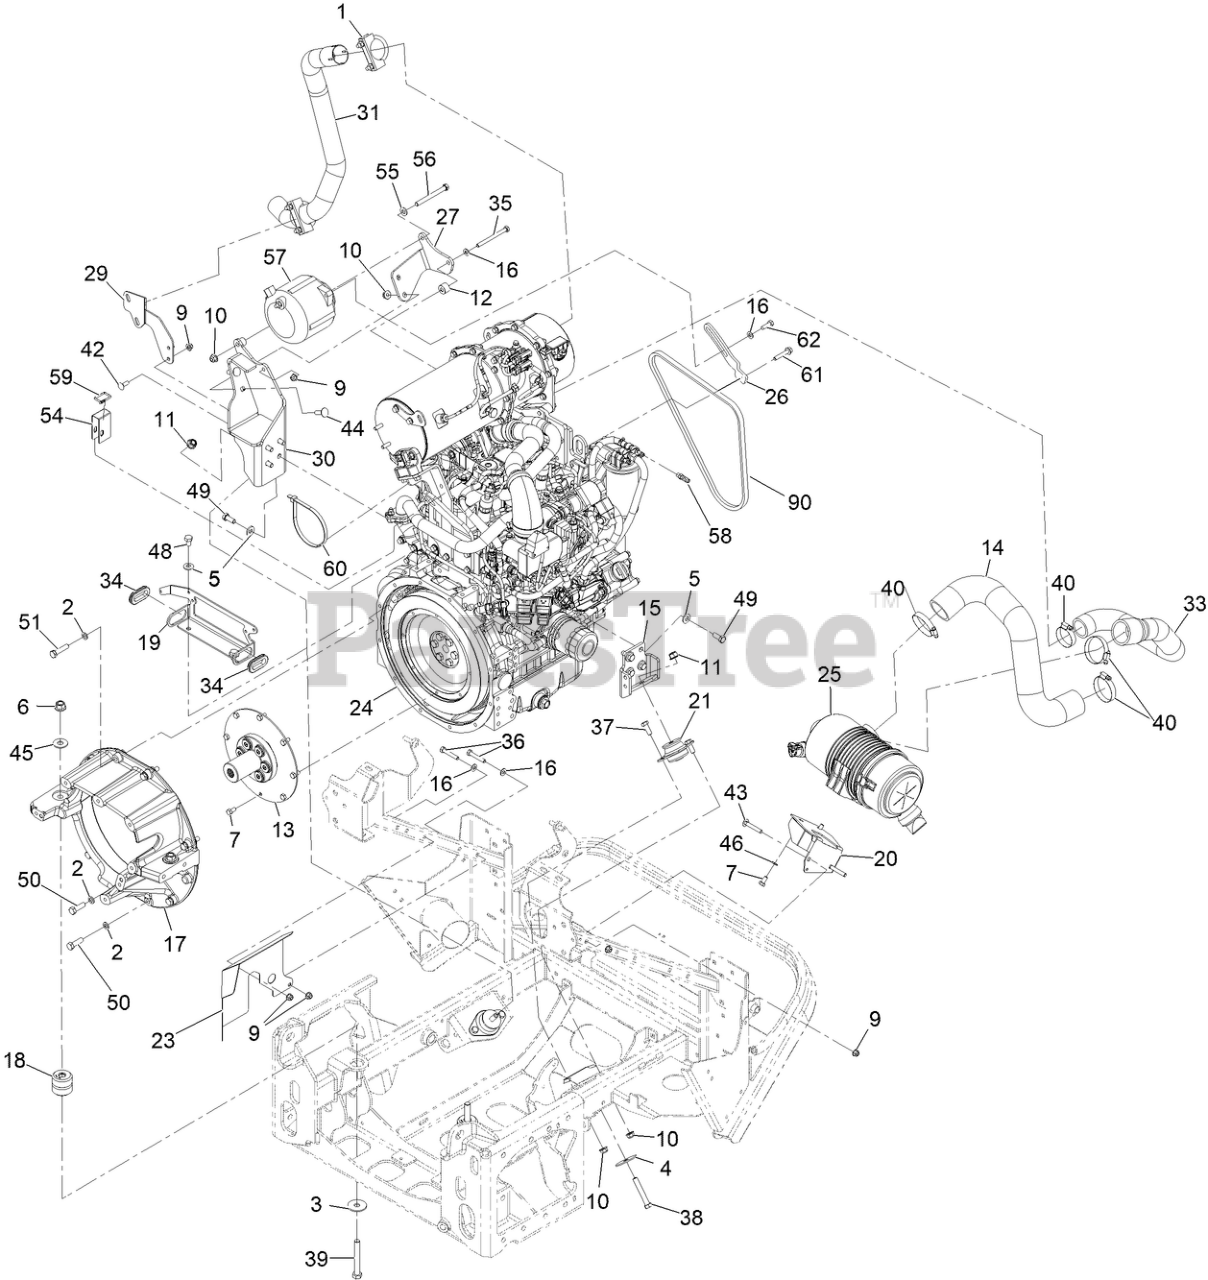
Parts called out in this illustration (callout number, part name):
2	WASHER-LOCK
3	WASHER-THRUST
4	WASHER-SNUBBING
5	WASHER-BELLEVILLE
6	Nut-Lock 1/2-13
7	BOLT
9	NUT-HF, NI
10	NUT-HF, NI
11	NUT-HF, NI
13	COUPLING-FLYWHEEL
14	HOSE-AIR
15	MOUNT-MOTOR, UPPER
16	WASHER-PLAIN
17	HOUSING-FLYWHEEL
18	Mount-Isolator
19	PLATE_GUIDE BRACKET
20	BRACKET-CLEANER, AIR
21	Mount- Isolator, Engine
23	SHEET-AIR DEFLECTOR
24	ENGINE-YANMAR, 3TNV86CT-DTR2
25	ASM, HDAC
26	TENSION ARM-ALTERNATOR
27	BRACKET, ALTERNATOR
29	EXHAUST BRACKET
30	MOUNT ASM-UPPER [BLACK]
31	TUBE-EXHAUST
33	HOSE-AIR
34	GROMMET-RUBBER
35	SCREW-HH
36	SCREW-HH
37	SCREW-HH
38	SCREW-HH
39	SCREW-HH
40	CLAMP-HOSE
42	SCREW-CARR
43	BOLT-CARR
44	BOLT-CARR
45	WASHER-FLAT
46	WASHER-BELLEVILLE
48	SCREW-HH
49	SCREW-HH
50	SCREW-HH
51	SCREW-HH
54	INSULATION-HEAT
55	WASHER-HARDENED
56	SCREW-HH 3/8-16 X 3 3/4 GR 8
57	ALTERNATOR-12V 175A
58	FITTING-STRAIGHT
59	TIE-CABLE, SS
60	TIE-CABLE
61	SCREW-HHF
62	SCREW-HH
90	BELT-V, COGGED
